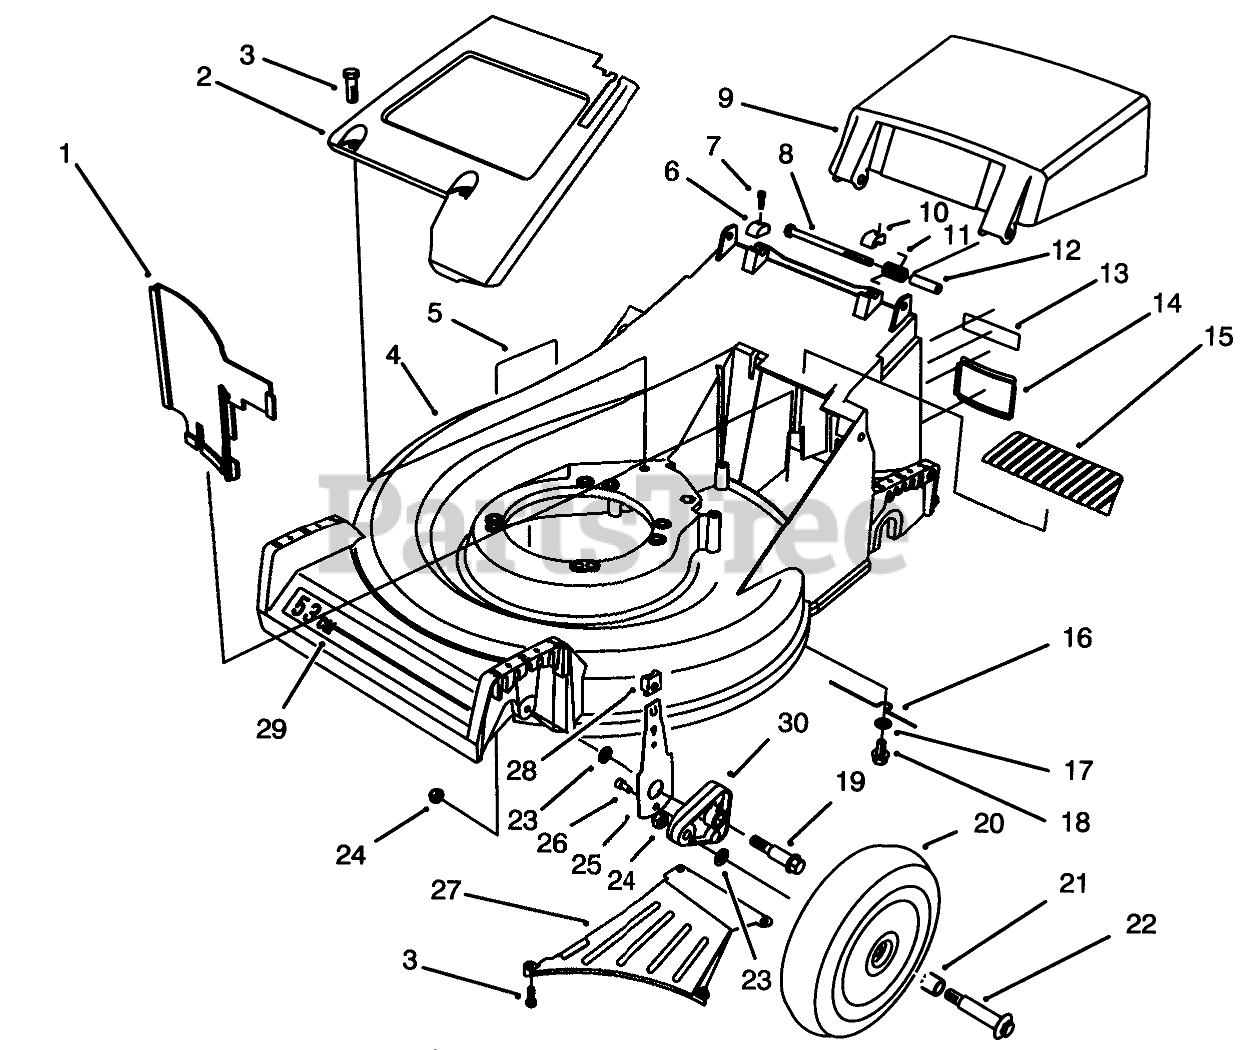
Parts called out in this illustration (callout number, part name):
1	PANEL-VERTICAL
2	PaneI-Screen
3	SCREW-HWHTF
4	Housing-53cm (Incl. Ref. #5 & 29)
5	Decal Danger
6	CAP-HINGE BOLT, RH
7	SCREW-HSH
8	SCREW-HH
9	Door Discharge
10	CAP-HINGE BOLT, LH
11	SPRING-DOOR
12	SPACER-DOOR
13	DECAL FRENCH REGUL.
14	COVER-ACCESS
15	COVER-TOP
16	RETAINER-BELT
17	WASHER-FLAT
18	SCREW-HHFTF
19	BOLT-SHOULDER
20	Wheel & Tire Assembly (Incl. Ref. #21)
21	BUSHING
22	WHEEL BOLT
23	WASHER
24	NUT-LOCK
25	FRONT SPRING ARM ASM
26	SCREW-HSH, THREAD FORMING
27	Ramp-Discharge
28	KNOB-ARM
29	DECAL
30	ARM-PIVOT, FRONT
